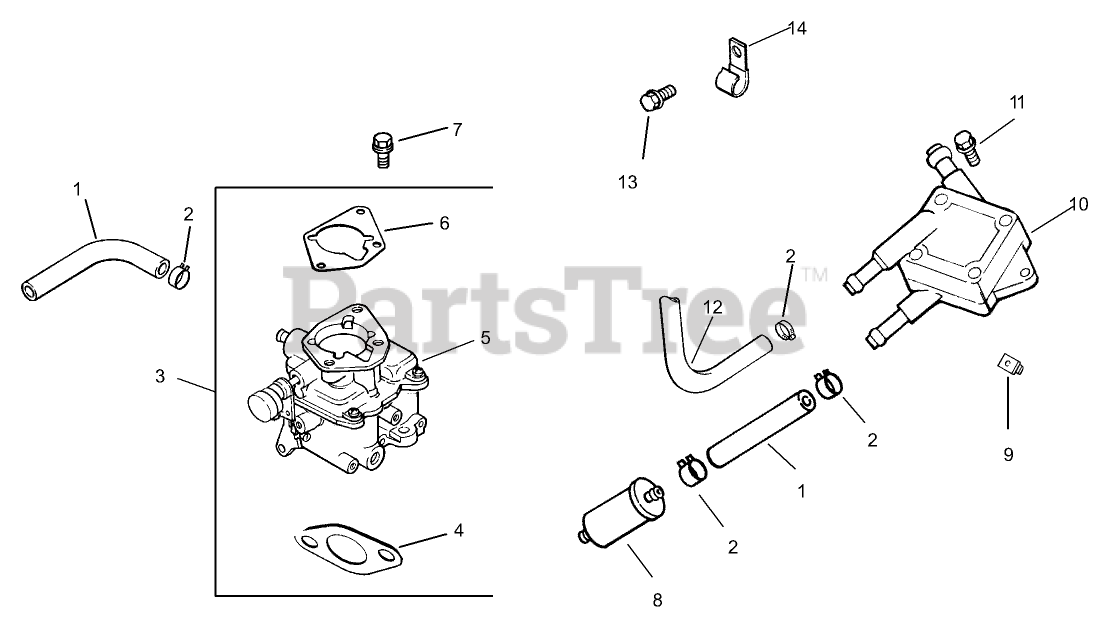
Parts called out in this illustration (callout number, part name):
1	Line-Fuel (9.5)
2	CLAMP-HOSE, SPRING (1/2)
3	Kit, carburetor w/gasket (Incl. Ref. #4-6)
4	GASKET-BASE, AIR CLEANER
5	Carburetor ASM (For information only not available separately)(Service with: 24 757 01-S, 24 757 02-S, 24 757 03-S, 24 757 08-S, 24 757 07-S, 24 757 09-S)
6	Gasket-Carburetor
7	SCREW-FLANGE (M6X1.0X30)
8	Filter-Fuel
9	Nut-Plastic
10	PUMP-FUEL
11	SCREW-TAP (M6X1.7X18)
12	Line-Fuel, Flexible (15.5)
13	Screw-HF (M6x1.0x12)
14	CLIP-CABLE
